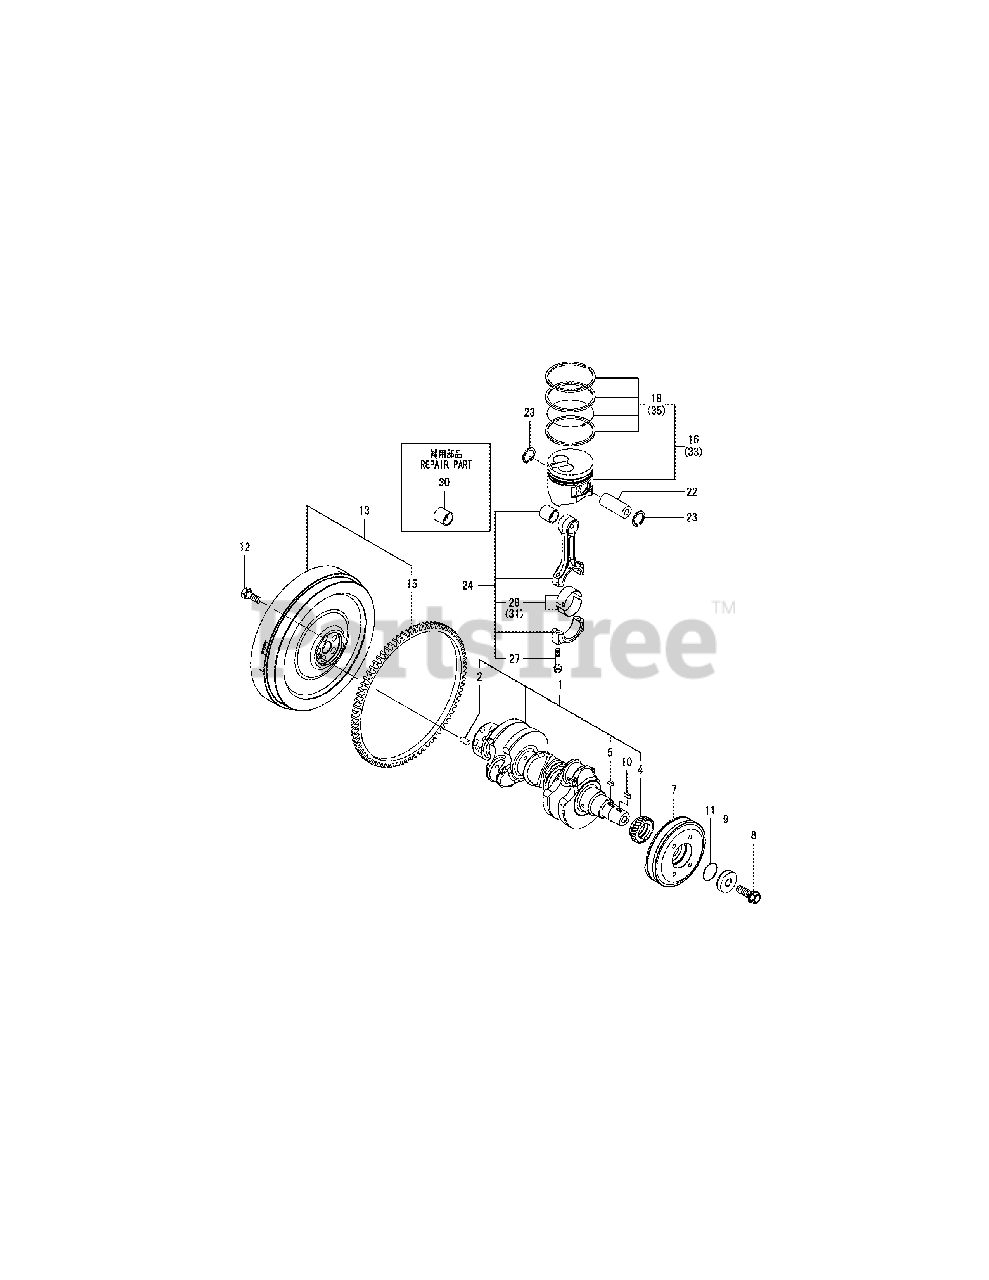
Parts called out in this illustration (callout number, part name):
1	CRANKSHAFT ASSY
4	GEAR, CRANKSHAFT
7	V-PULLEY, CRANKSHAFT
8	BOLT M12X1.25,FLANGE
11	O-RING 1A S-34.0
12	BOLT, FLYWHEEL
18	RING SET, PISTON
24	ROD ASSY, CONNECTING
27	BOLT, CONNECTING ROD
28	METAL ASSY,CRANK PIN
30	METAL, PISTON PIN
31	METAL, CRANK PIN .25
35	RING SET O.S=0.25
